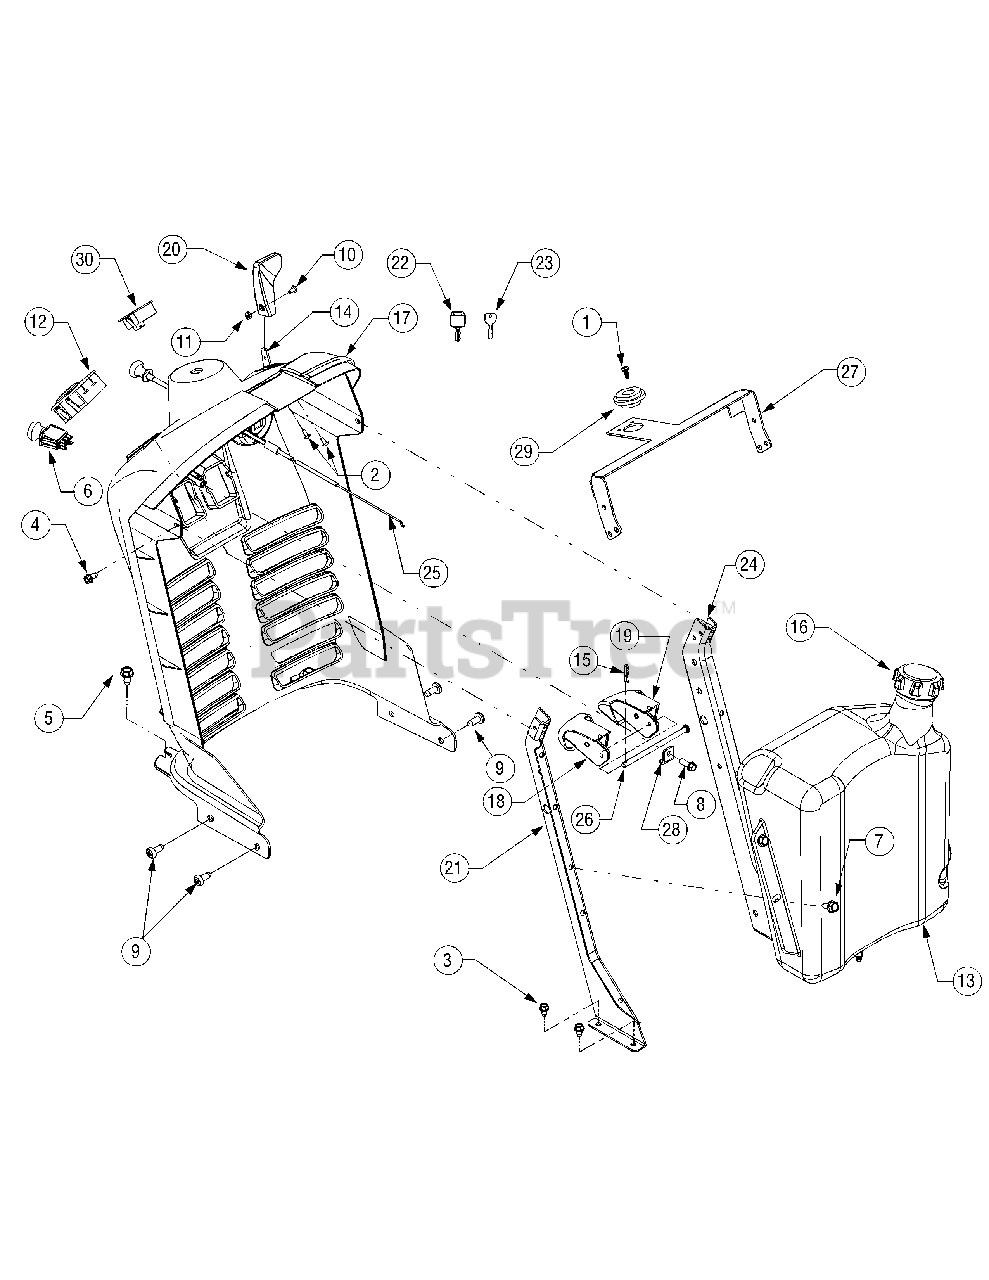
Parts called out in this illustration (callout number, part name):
1	Screw, #10-16 x .50
2	Screw, #10-24 x .375
3	Screw, Self-tapping, 1/4-20, 0.5
4	Screw, Hex. 1/4-20 x .375
5	Screw, Hex, 5/16-18, .50
6	Switch, PTO
7	Screw, Hex, 5/16-12 x .75
8	Screw, 1/4-15, 0.750
9	Screw, Torx Hd. , 5/16-18 x .75
10	Screw, Machine, #8-32, 0.375,
11	Nut, #8-32
12	Switch Module, Ignition
13	Fuel Tank, 3 Gal
14	Control, Throttle, 27.4
15	Internal Cotter Pin, .072 x 1.13
16	Cap, Fuel
17	Dash
18	Lever, Dash, Cruise
19	Lever, Dash, Brake
20	Knob, Throttle Control
23	Ignition Key, Metal
25	Control, Choke, 24.0
26	Rod, .250 Dia x 4.25 Lg.
29	Steering Colume Bearing
30	Monitor, Systems Indicator / Hour
